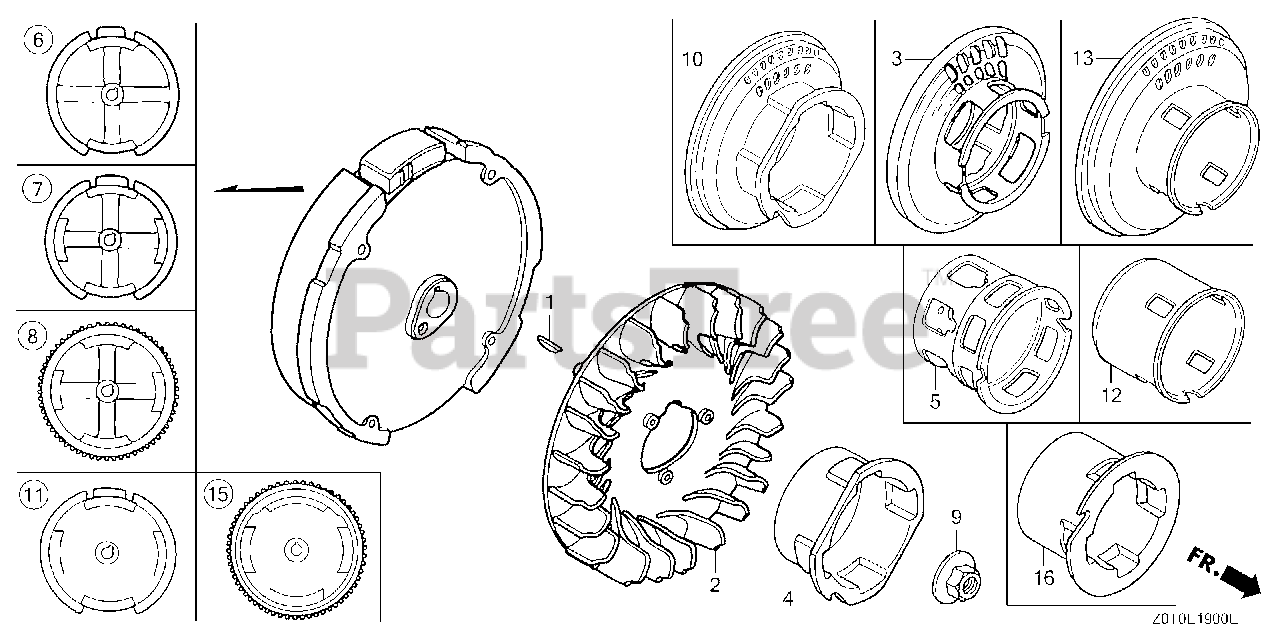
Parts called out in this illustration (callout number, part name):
1	KEY, SPECIAL WOODRUFF (25X18)
2	FAN, COOLING
4	PULLEY, STARTER
8	FLYWHEEL (STARTER MOTOR)
9	NUT, SPECIAL (14MM)
12	PULLEY, STARTER
